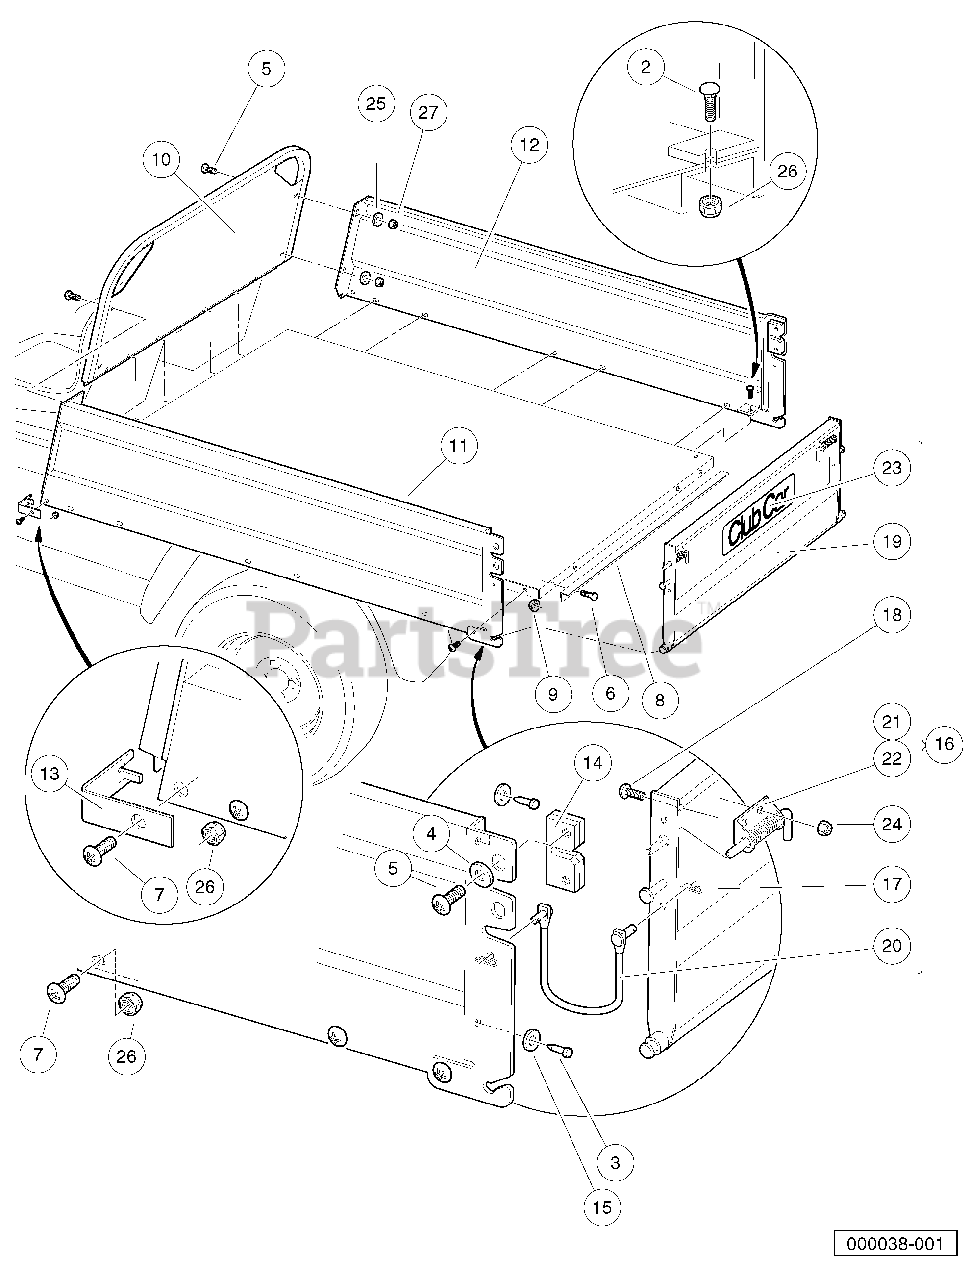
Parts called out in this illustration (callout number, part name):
1	Instl, Steel Box, XRT
2	Bolt, Carriage, 5/16-18 X 1.00
3	Bumper, Rubber
4	Washer, 1/4" Type B Flat
5	Screw, 1/4-20 X 0.75 Torx Truss-Head
6	Stud, Self-Clinching Flush Head
7	Screw, 5/16-18 X 0.88 Torx Truss-Head
8	Box Bed Tailgate Angle
9	Locknut, 5/16-18 Hex Flange
10	Front Panel Weldment
11	Left Panel Weldment
12	Right Panel Weldment
13	Front Corner Cap
14	Slam Latch
15	Washer, Rubber, 3/8
16	Assembly, Tailgate
17	Hair Pin Clip
18	Screw, 1/4-20 X 0.75 Torx Truss-Head
19	Tailgate, Weldment
20	Tether Assembly
21	Spring Latch Left
22	Spring Latch Right
23	Decal, Club Car Tailgate
24	Locknut, 1/4-20 Nylon Insert
25	Washer, 1/4 Type A Narrow Flat
26	Locknut, 5/16-18 Nylon Insert
27	Locknut, 1/4-20 Nylon Insert
